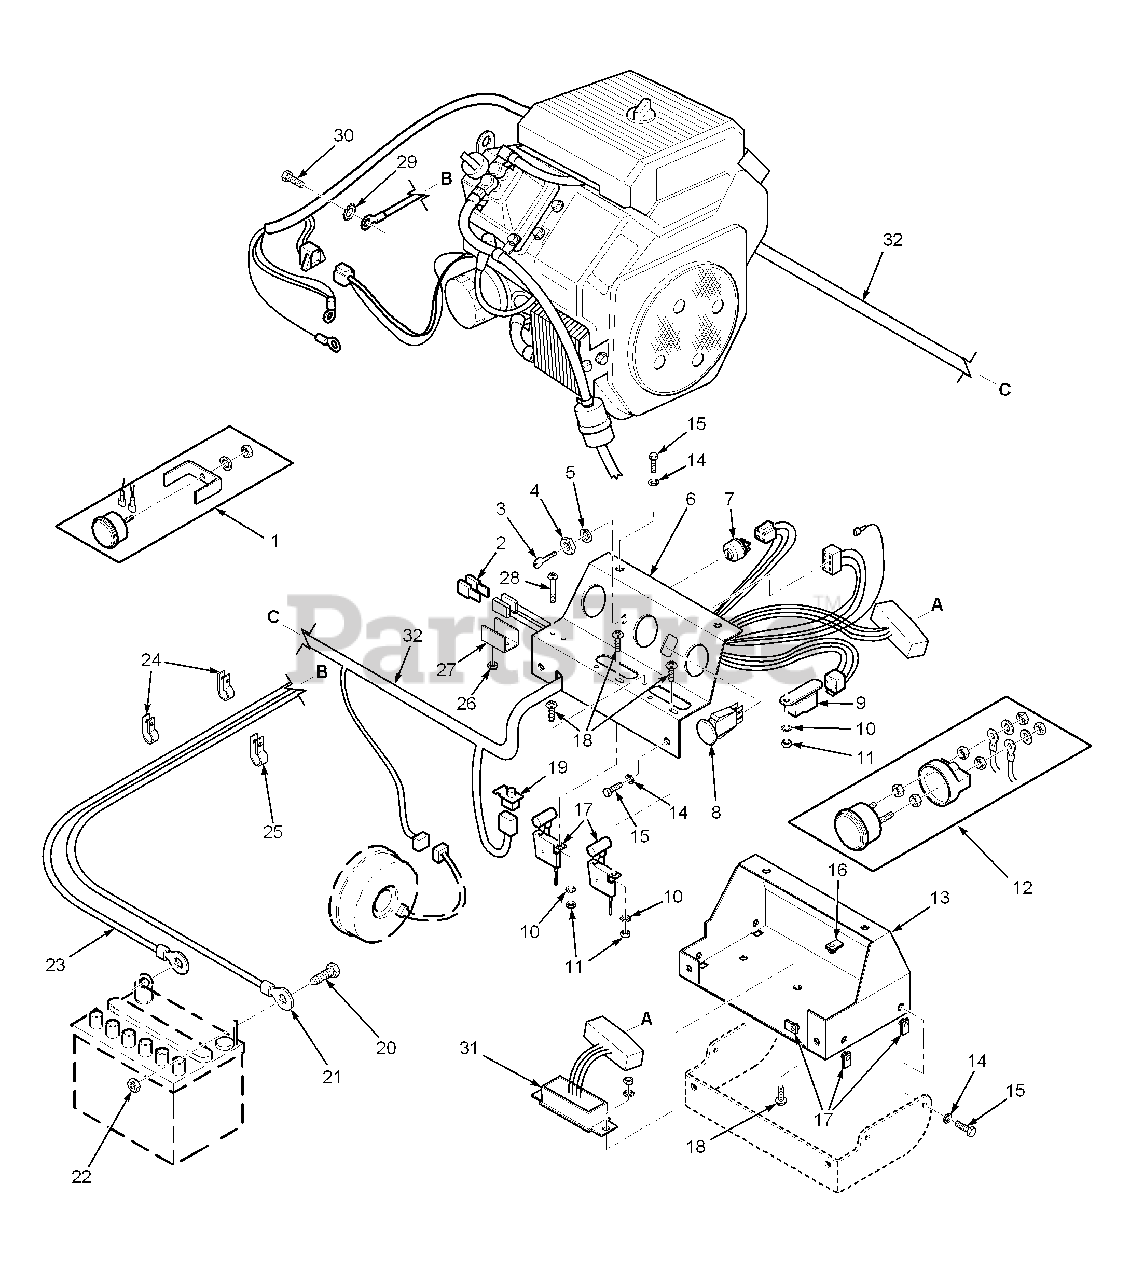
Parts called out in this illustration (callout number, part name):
1	Hour Meter
2	Fuse, 20 AMP
3	Key & Ring Assembly
4	Nut, Hex 5/8-32
5	Lockwasher, 5/8" Internal
6	Instrument Panel, Top W/Decals
7	Key Switch
8	Switch, PTO
9	Relay
10	Lockwasher, #10 External Tooth
11	Nut, Hex #10-32
12	Ammeter
13	Base, Instrument Panel
14	Lockwasher, 1/4"
15	Bolt, Hex Head 1/4-20 x 3/4"
16	U-Nut, 1/4-20
17	Throttle And Choke Controls
18	Screw, Phillips Washer Head #10-32 x 1/2"
19	Switch, Interlock-Seat
20	Bolt, Hex Head 1/4-20 x 1/2"
21	Cable, Battery - Red 20"
22	Nut, Hex 1/4-20
23	Cable, Battery - Black
24	Clamp, Cable 1/2" ID.
25	Clamp, Cable 3/4" ID.
26	Nut, Hex Elastic Stop #10-32
27	Bracket, Fuse Holder
28	Screw, Phillips Washer Head #10-32 x 1-1/2"
29	Lockwasher, 5/16" External Tooth
30	Bolt, Hex Head M8-1.25 x 20
31	Electronic Module
32	Wire Harness, STT
